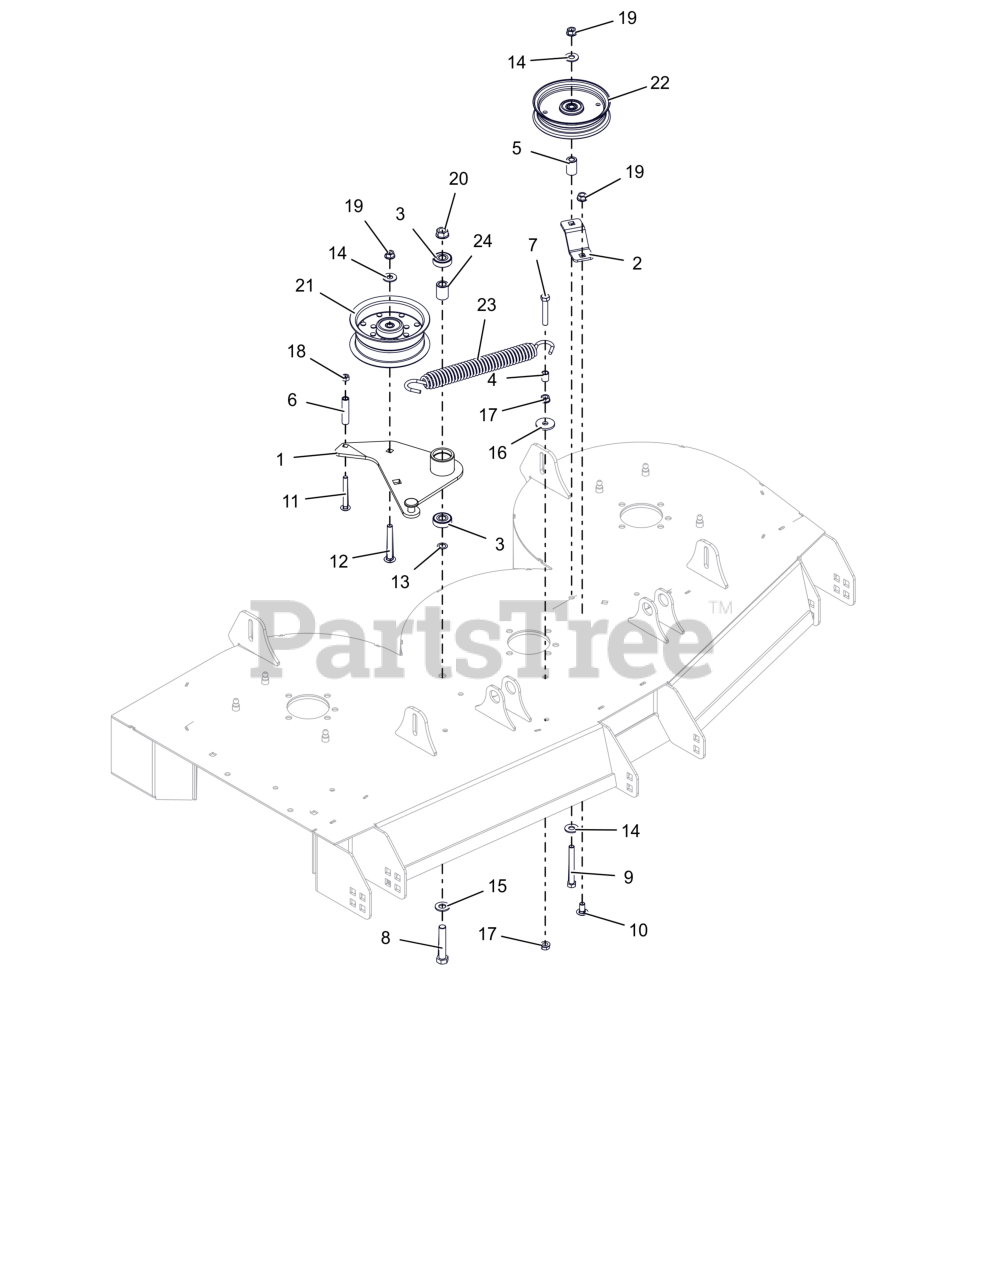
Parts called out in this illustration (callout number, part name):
1	WLDMT- IDLER ARM
2	PTO FIXED IDLER MTG BRKT-ORG
3	BRG-BALL .500X1.38X.437
4	SPCR, SLV .385X.500X.652
5	BUSHING, SLV .380X.750X1.190
6	SPCR- .331 X .500 X 2.190
7	BLT,HEX .38-16X2.25 G5 ZCC
8	BLT,HEX .50-13X2.75 G5 ZCC
9	BLT, HEX .38-16X3.25 G5 ZCC
10	BLT, RHSSN .38-16X.75 G5 ZCC
11	BLT,RHSN .313-18 X 2.75 G5 ZCC
12	BTL,RHSSN .375-16 X 3 G5 ZCC
13	WASHER, .500X.750X.020 THRUST
14	WSHR,FLT .438X1.00X.083 ZCC
15	WSHR,FLT .531X1.062X.095 ZCC
16	WSHR,FLT .406X1.375X.135 ZCC
17	NUT, SPNLK-FLG .38-16 G5 ZCC
18	NUT,LK-CTR .31-18 GA ZCC
19	NUT-LK-CTR-FLG .375-16 GF ZCC
20	NUT-LK-CTR-FLG .500-13 GG ZCC
21	PULLEY, FLAT 5.00X2.36X.375
22	IDLER- FLAT - 5.00" X .75"
23	SPRING, EXTENSION
24	SPACER .510 X .867 X 1.1485
